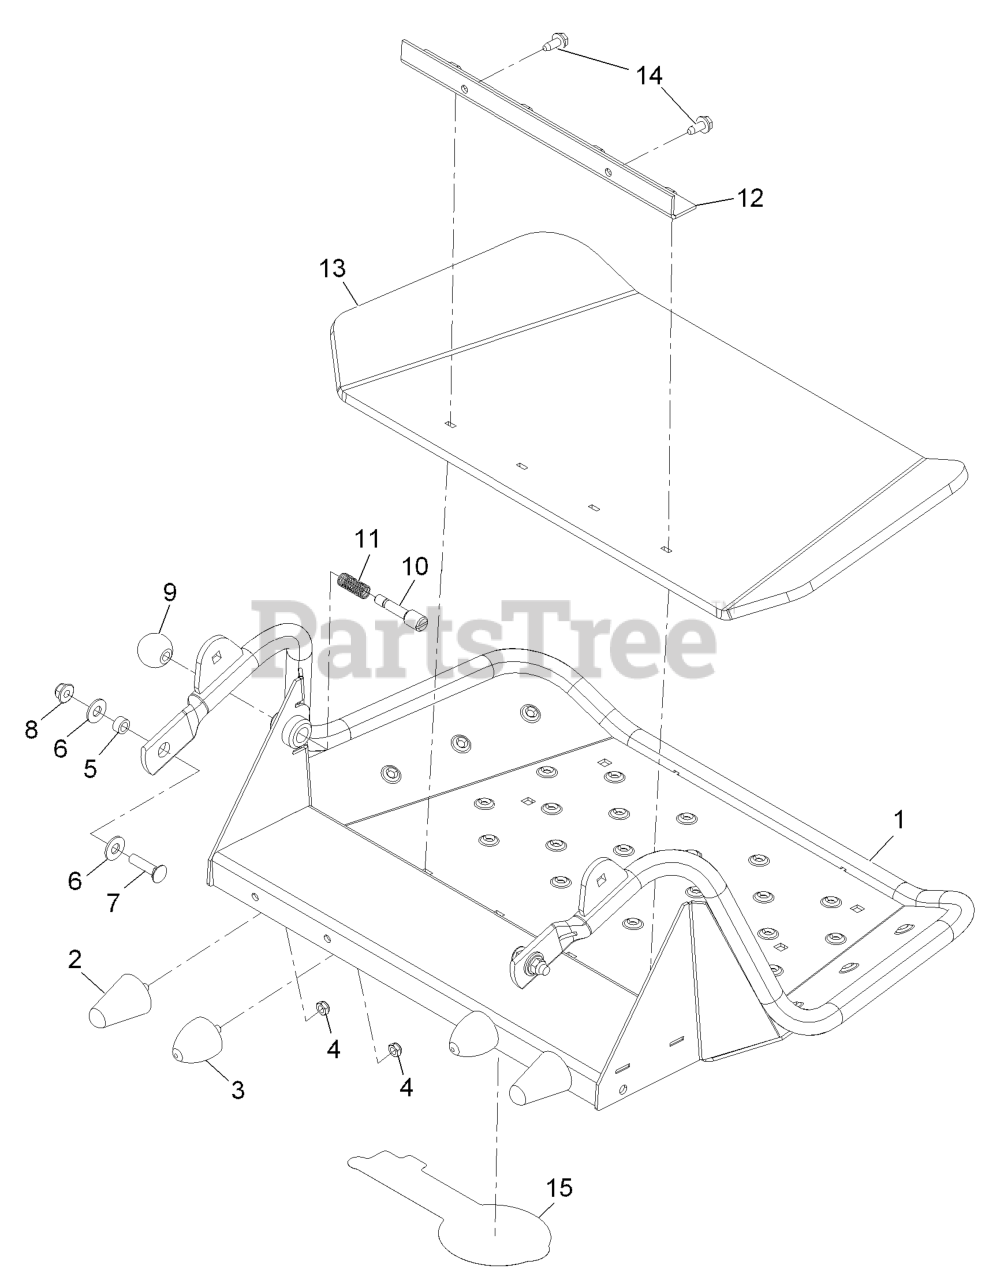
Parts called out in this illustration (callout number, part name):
1	PLATFORM ASM
2	BUMPER-RUBBER
3	BUMPER-RUBBER
4	NUT-LOCK, NI
5	SPACER
6	WASHER-FLAT
7	SCREW-CARR
8	NUT-HF, NI
9	KNOB-BALL
10	PIN-LATCH
12	CLAMP-SHIELD
14	Screw-HWH 5/16-18 X 3/4 Tf
15	DECAL, EXMARK LOGO
